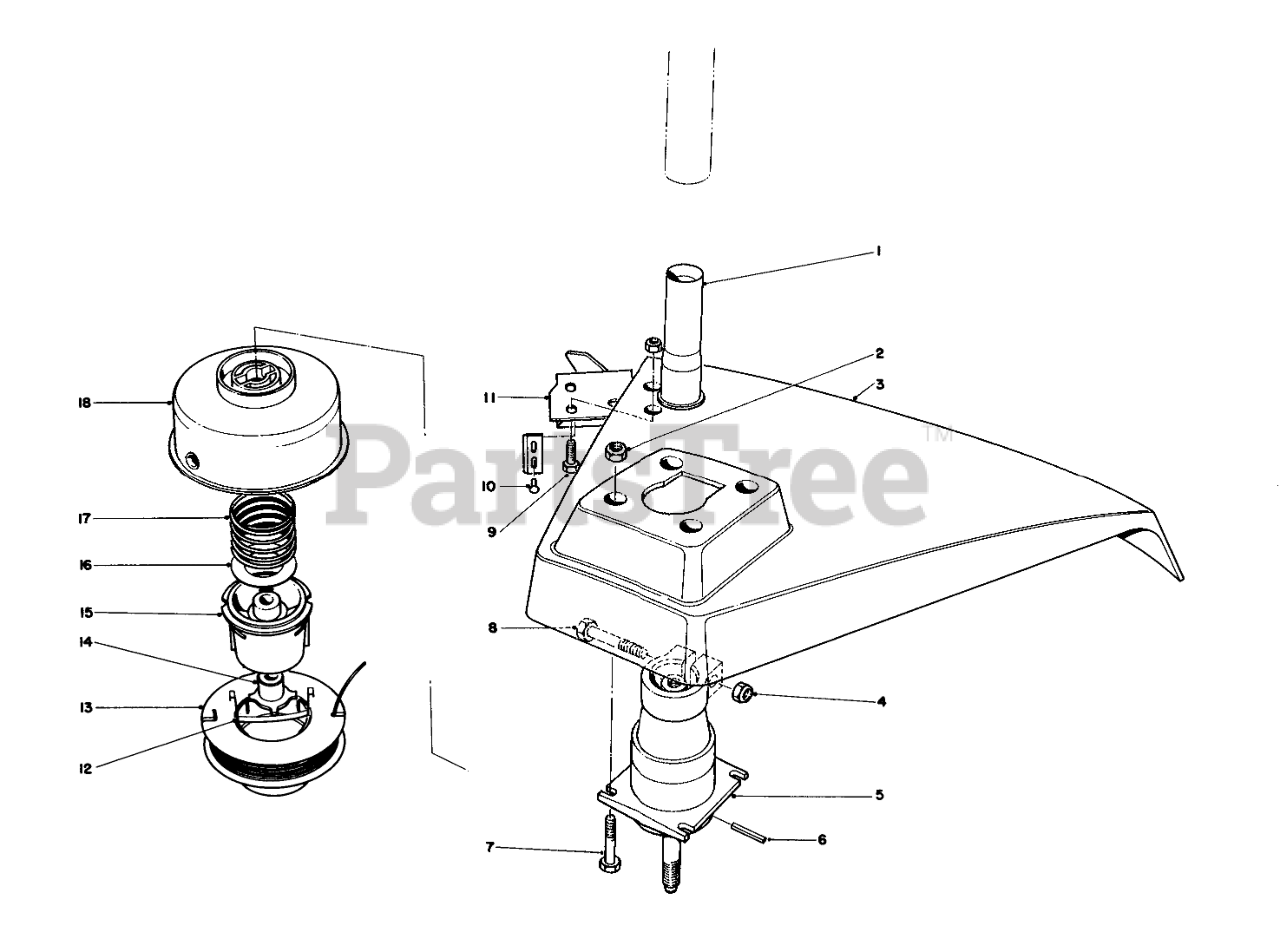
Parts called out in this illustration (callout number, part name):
1	INSERT-POLE END
2	NUT-LOCK, NI
3	Shield
4	NUT-LOCK, NI
5	Bearing Housing Assembly
6	COIL PIN
7	SCREW-HH
8	SCREW-HH
9	SCREW-HWH
10	Pop Rivet
11	Knife Blade Assembly (Incl. Ref. #10)
12	SADDLE-SPOOL CAP
13	Empty Spool
14	DRIVER
15	SPOOL CORE
16	WASHER-FLAT
17	SPRING COMPRESSION
18	DRUM/EYELET
